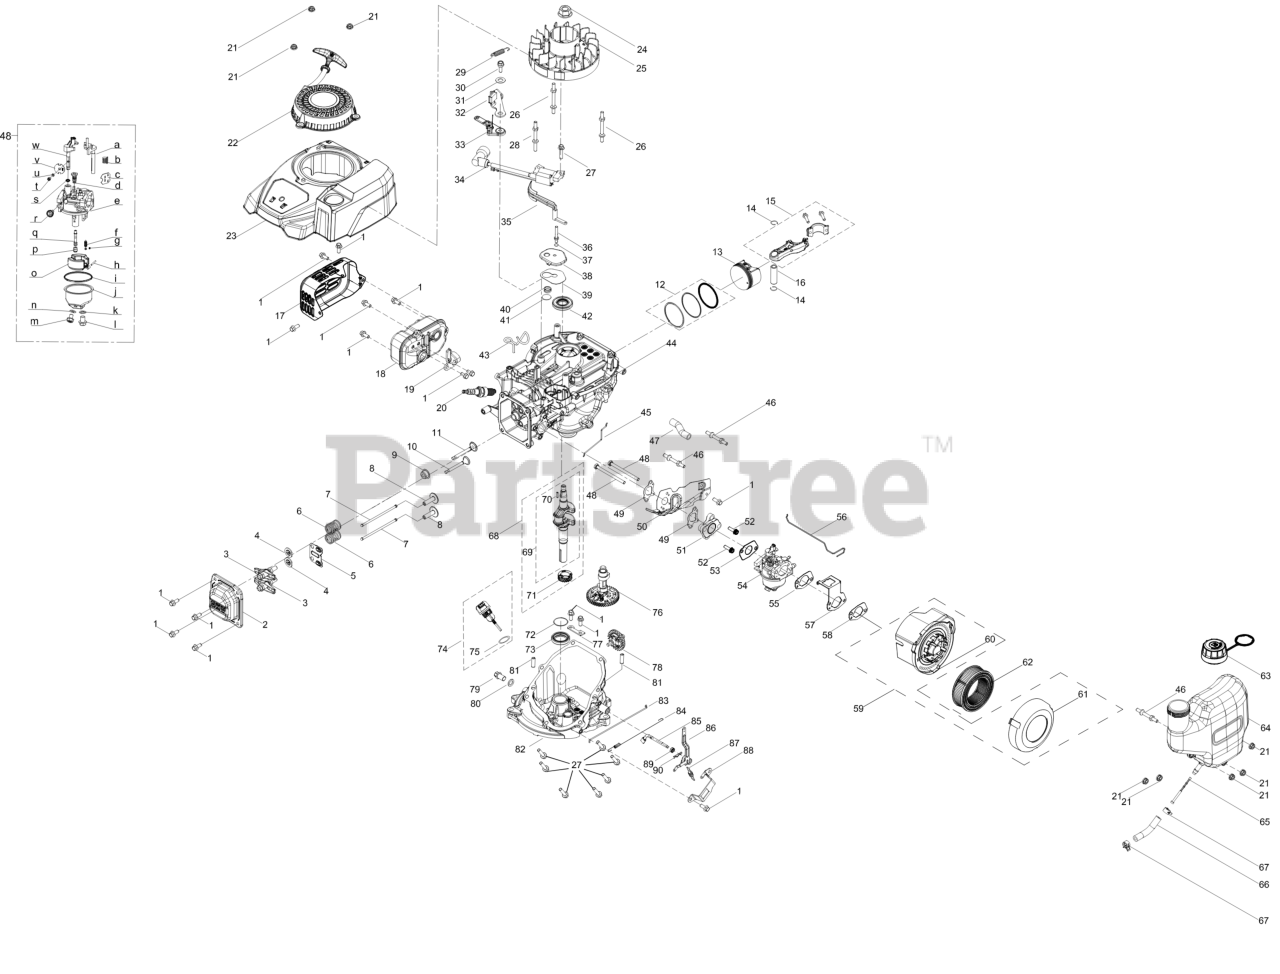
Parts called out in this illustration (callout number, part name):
1	BOLT M6-1 x 14 GR8.8
2	VALVE COVER
3	ROCKER ARM ASSEMBLY
4	VALVE SPRING RETAINER
5	PUSH ROD GUIDE
6	VALVE SPRING
7	PUSH ROD GUIDE
8	TAPPET (LIFTER)
9	INTAKE VALVE SEAL
10	EXHAUST VALVE
11	INTAKE VALVE
12	PISTON RING SET
13	PISTON
14	WRIST PIN CLIP
15	CONNECTING ROD ASSEMBLY
16	PISTON PIN
17	MUFFLER GUARD
18	MUFFLER ASSEMBLY
19	CHOKE CONTROL THERMOSTAT
20	SPARK PLUG
22	RECOIL STARTER
23	ENGINE SHROUD
24	FLYWHEEL NUT
26	SHROUD STUD M6x85
27	BOLT M6-1 x 25 GR8.8
28	SHROUD STUD M6x83
29	ENGINE BRAKE SPRING
30	ENGINE BRAKE PIN M6-1.0 MM
31	FLAT WASHER 10x20x1.0 MM
32	ENGINE BRAKE ARM
33	ENGINE BRAKE LOWER BRACKET
34	IGNITION COIL
36	PIVOT VANE STUD
37	FLAT WASHER 6x1x18
38	BREATHER COVER PLATE
39	BREATHER GASKET
40	BREATHER VALVE SPRING
41	BREATHER VALVE
42	UPPER CRANKSHAFT SEAL
43	IGNITION WIRE SUPPORT
45	CHOKE LINKAGE
46	FUEL TANK MOUNTING STUD M6X59.5
47	BREATHER HOSE
48	BOLT M6X80
49	CARBURETOR GASKET
50	CARB HEAT SHIELD
51	CARBURETOR INSULATOR
52	BOLT M6X20
53	CARBURETOR GASKET
54	Carburetor Assembly
55	AIR FILTER BRACKET GASKET
56	TEMP CONTROL LINKAGE
57	CHOKE TEMP CONTROL BRACKET
58	AIR FILTER BASE GASKET
59	AIR FILTER ASSEMBLY
60	AIR FILTER BASE
61	AIR FILTER COVER
62	PAPER AIR FILTER
62	Genuine Factory Parts AIR FILTER
63	FUEL CAP W/TETHER
65	FUEL FILTER
65	Genuine Factory Parts FUEL FILTER
66	FUEL HOSE
67	HOSE CLAMP
68	CRANKSHAFT ASSEMBLY
69	CRANKSHAFT ASSEMBLY
70	WOODRUFF KEY
71	CRANKSHAFT TIMING GEAR
72	THRUST WASHER
73	LOWER CRANKSHAFT SEAL
74	DIPSTICK ASSEMBLY
75	DIPSTICK SEAL
76	CAMSHAFT ASSEMBLY
77	GOVERNOR GEAR MOUNTING PLATE
78	GOVERNOR GEAR/SHAFT ASSEMBLY
79	OIL DRAIN PLUG
80	FLAT WASHER
81	DOWEL PIN 7X20
82	CRANKCASE COVER
83	THROTTLE LINKAGE
84	THROTTLE LINKAGE SPRING
85	GOVERNOR ARM SHAFT
86	GOVERNOR ARM ASSEMBLY
87	GOVERNOR SPRING
88	COMPONENT BRACKET
89	GOVERNOR SEAL
